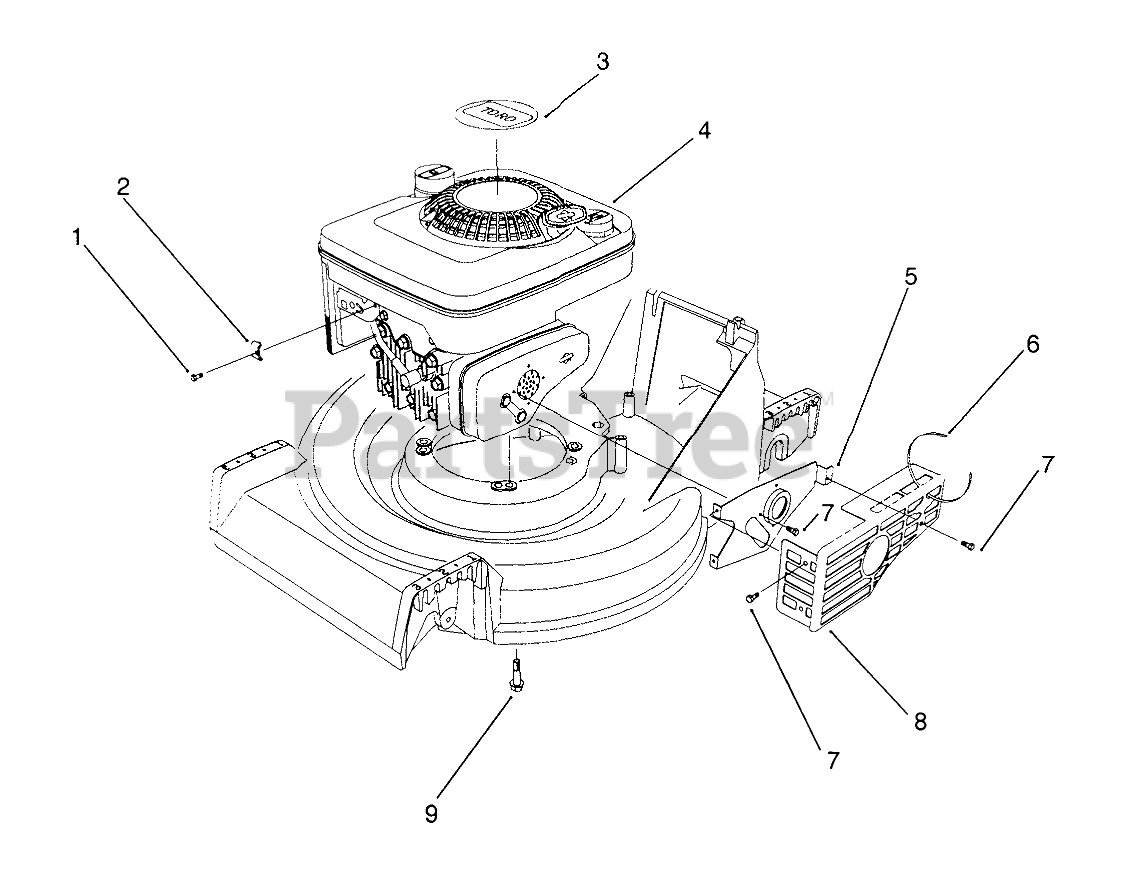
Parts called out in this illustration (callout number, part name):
1	Screw
2	CLAMP-CASING
3	DECAL - ENGINE
5	MUFFLER BRKT F/W
6	TIE-CABLE
7	SCREW W/ENGINE
8	MUFFLER GUARD F/W
9	SCREW-HWH
